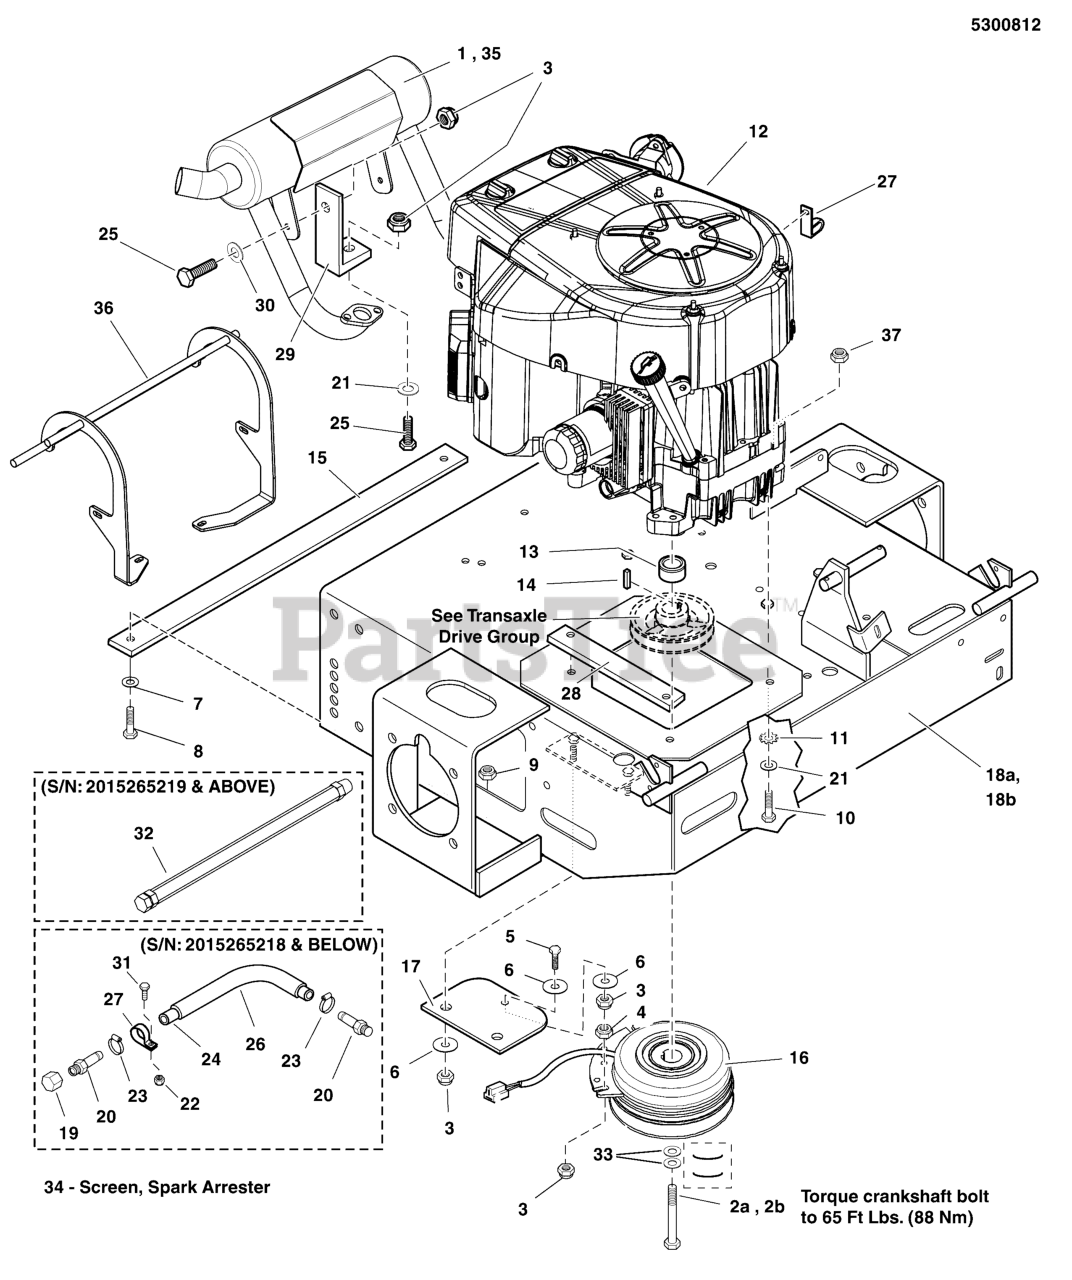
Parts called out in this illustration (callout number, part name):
1	MUFFLER
3	NUT, 5/16-18 HEX NYLOCK FLANGE
4	NUT, 5/16-18 HEX SERRATED FLANGE (LARGE)
5	BOLT, 5/16-18 X 2-1/4 TFL, GD5 YZ
6	WASHER, .34 X 1.25 X 10 GA
7	WASHER, 1/2" GD9 YZ
8	BOLT, 1/2-20 X 1-1/4" GD5 CZ
9	NUT, Hex, Nylon Lock, 1/2-20
10	BOLT, 5/16-24 X 1-3/4, GD8
11	WASHER, 5/16" INT. TOOTH LOCK
12	ENGINE, BRIGGS & STRATTON
13	SPACER, 1.13 X 1.75 X 1.347
14	KEY, 1/4" SQ. X 1.25
15	TIE BAR - RED
16	*CLUTCH, 5218-134, WARNER
17	CLUTCH ANCHOR PAD
19	CAP, 3/8" NPT
20	FITTING, 3/8NPT-1/2" HOSE. STR
21	WASHER, 5/16" SAE
22	NUT, 1/4-20 HEX SERR. FLANGE
23	CLAMP, #6 HOSE, STAINLESS
24	HOSE, 1/2" PUSH-ON, 18.50"
25	BOLT, 5/16-18 X 1"
26	WIRE LOOM, 3/4" ID, 16.00
27	CLAMP, VINYL INSULATED
28	SPACER, ENGINE BLOCK
29	BRACKET, MUFFLER - RED
30	WASHER, 5/16" GD.9 FLAT
31	BOLT, 1/4-20 X 3/4" GD5 YZ
32	HOSE, OIL DRAIN
33	BELLEVILLE WASHER 1.1875 X .442 X .089
34	SCREEN, SPARK ARRESTER
35	MUFFLER, 26/28, B&S VANG, TWR/WLK
36	WELD, MUFFLER GUARD, TWR-BLK
37	NUT, 5/16-24, NYLOCK FLANGE, GD8, CZ
